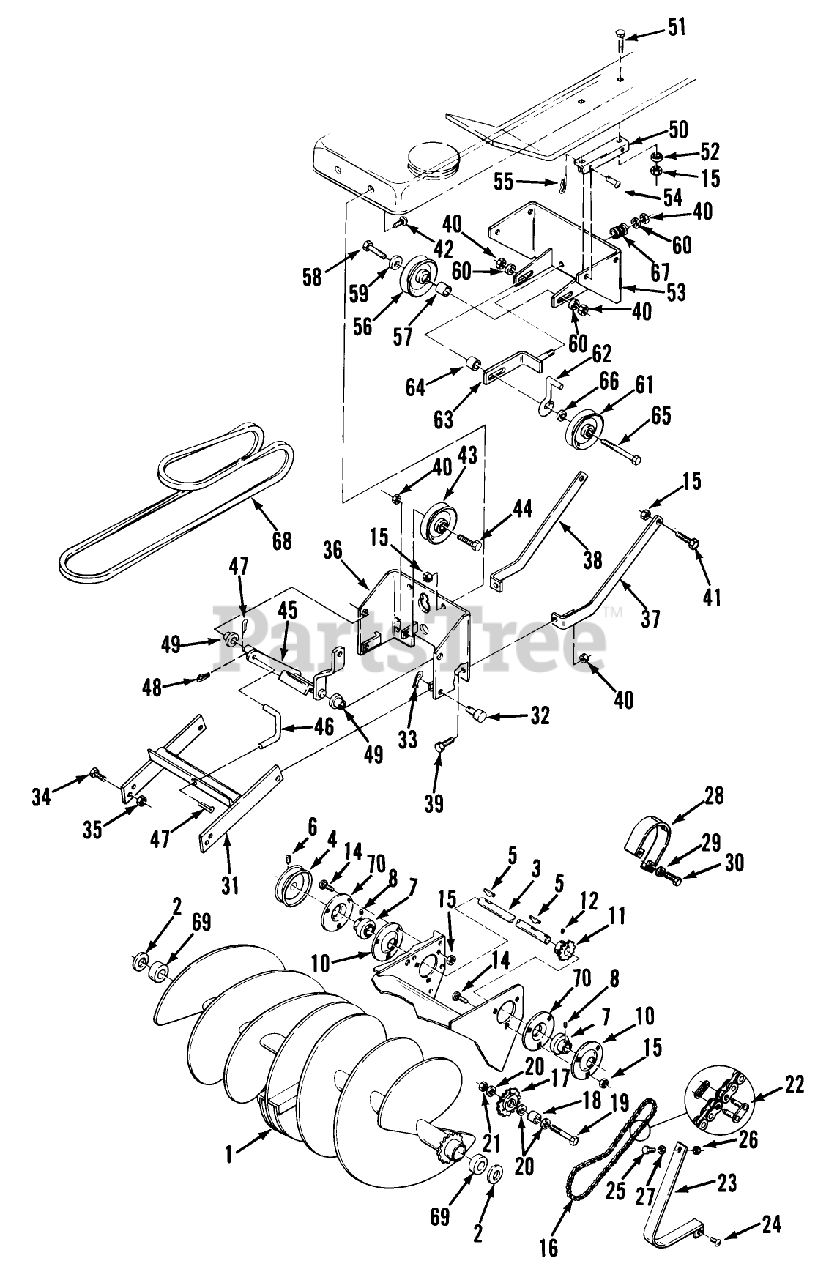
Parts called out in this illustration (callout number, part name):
3	SHAFT
4	PULLEY
7	BEARING AND COLLAR
10	FLANGE-ZERK RELUBE
18	SPACER
28	GUARD-CHAIN *R
30	Bolt
32	PIN
33	Hairpin Cotter
36	ASS'Y-FRONT SUPPO *R
38	BRACE-FRAME MT RH *R
48	Hairpin
49	BUSHING
52	WASHER 5/16 SAE
54	PIN
55	Hairpin
60	WASHER
64	SPACER
67	SPRING-COMPRESSION
69	BEARING-BALL
70	FLANGE
